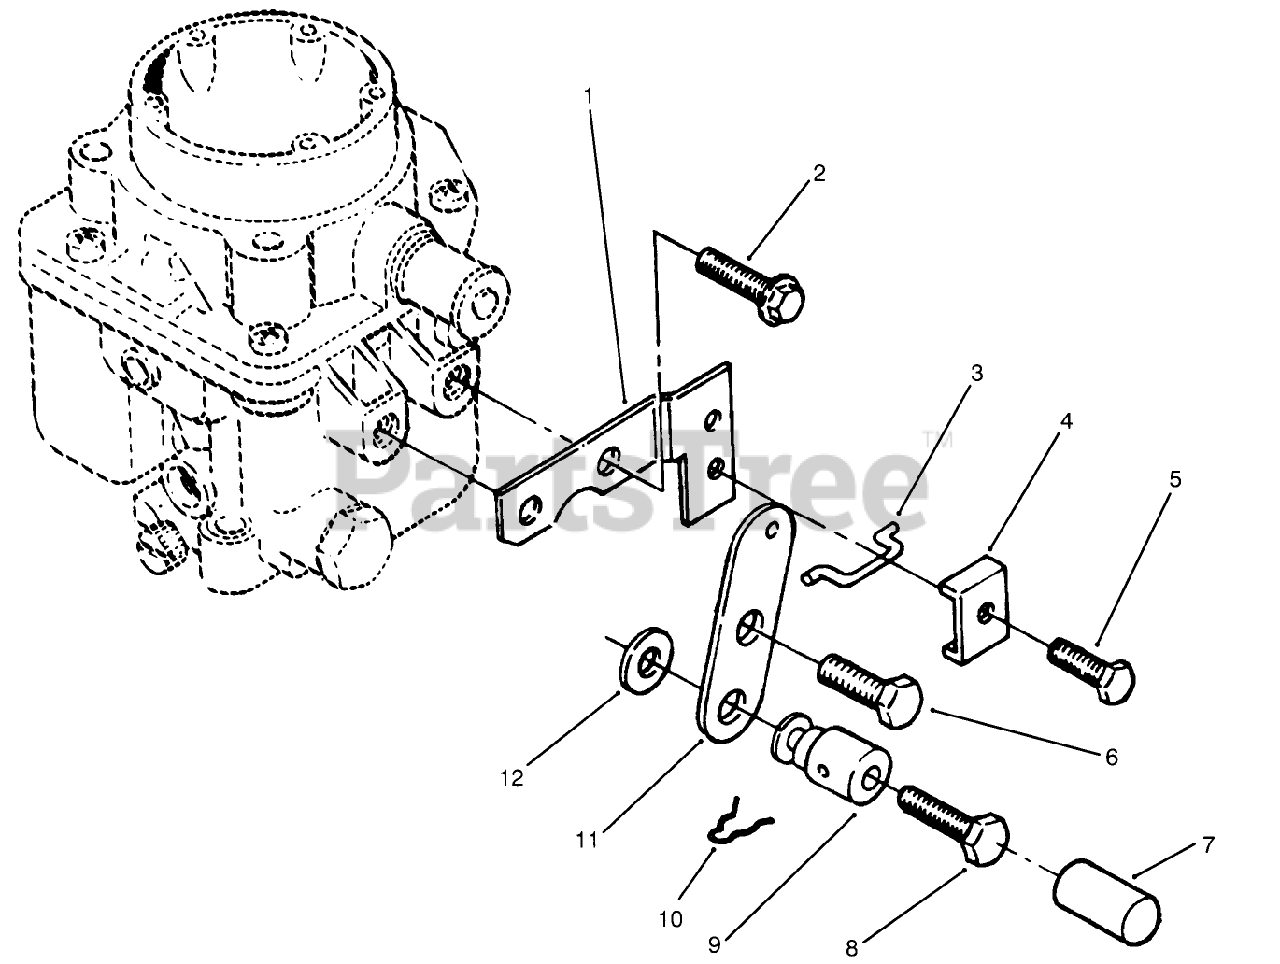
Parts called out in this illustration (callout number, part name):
1	BRACKET
2	SCREW-HWH
3	LINK-CHOKE
5	SCREW-TAPPING
6	MACHINE SCREW
8	SCREW
10	PIN-COTTER
